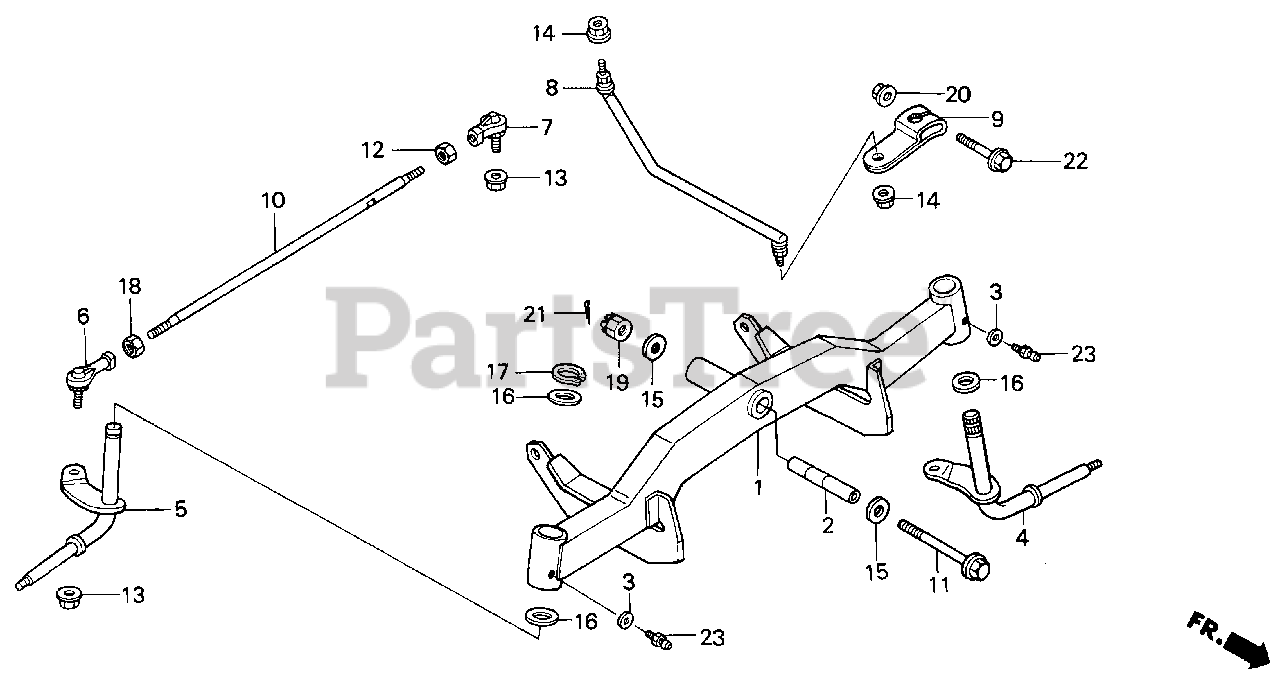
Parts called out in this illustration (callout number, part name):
1	AXLE, FR.
2	COLLAR, FR. AXLE
3	COLLAR (6.5X11X3)
4	KNUCKLE, L.
5	KNUCKLE, R.
6	JOINT, R. BALL
7	JOINT, L. BALL
9	ARM, KNUCKLE
11	BOLT, FLANGE (12X120)
12	NUT, L. HEX. (10MM)
13	NUT, AXLE (10MM)
14	NUT, FLANGE (12MM)
15	WASHER, PLAIN (12MM)
16	WASHER, THRUST (20MM)
17	CIRCLIP (OUTER) (20MM)
18	NUT, HEX. (10MM)
19	NUT, CASTLE (12MM)
20	NUT, FLANGE (8MM)
21	PIN, COTTER (3.0X45)
22	BOLT, FLANGE (8X50)
23	FITTING, GREASE (A.76)
